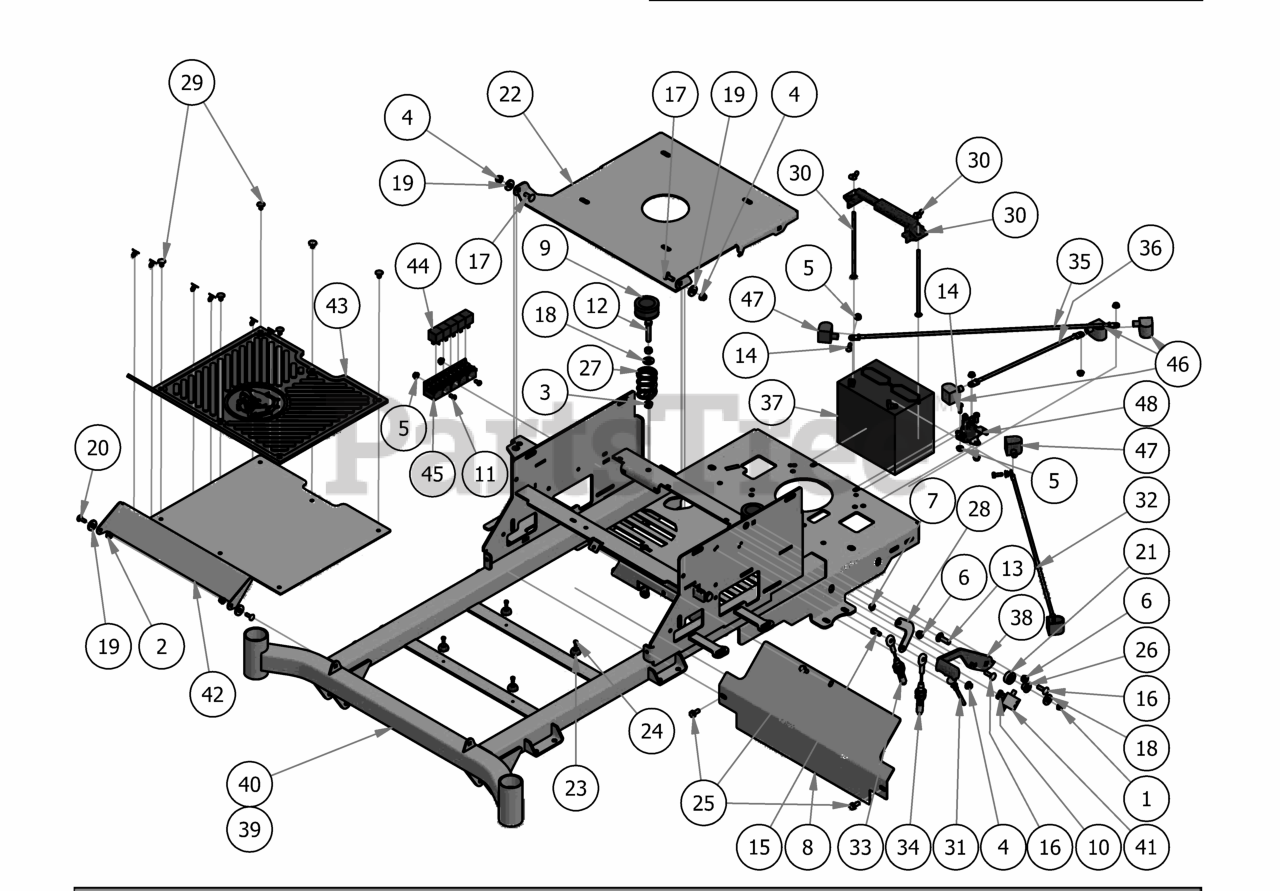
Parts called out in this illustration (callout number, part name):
1	3/8-16 Centerlock Half Nut
2	1/4-20 Nylon Insert flange Nut
3	3/8" Flange Nut
4	5/16-18 Nylong Flange Nut
5	1/4-20 Hex Flange Nuts Zinc w/Serrations
6	5/16-18 Hex Flange Nut
7	5/16-18 Nylock Jam Nut 1/2 Nut
8	2017 ZT Cooler Cover
9	Seat Spring Cap Cover
10	12-24x 1/2 HWH Bolt
11	1/4" x 1/2" BS C/S 18-8 SS
12	3/8'' x2'' Hex Bolt
13	3/8" x 1 1/4" Carriage Bolt
14	1/4" x 3/4" Hex Bolt
15	5/16" x 3/4" Hex Bolt
16	5/16" x 1" Carriage Bolt
17	5/16" x 7/8" Carriage Bolt
18	3/8" Flat Washer
19	.360 ID Plastic Washer
20	1/4" x 3/4" Carriage Bolt
21	2015 Brake Lever Spacer
22	Seat Plate 2016
23	Button Bumper
24	#10 x 1/2" Self Tapping Screw
25	5/16 x 3/4 washer head type F screw
26	Bronze Bushing SF-1220-8
27	Seat Spring
28	Brake Cable Adapter Bracket
29	5/8" Christmas Tree Fastener
30	Hold Down Assembly
32	24" Black Ground Cable
33	Brake Cable
34	Brake Cable
35	24" Red Battery Cable
36	12 in red battery cable
38	Brake Handle
39	ZT 54" and 60" Frame
40	ZT 48" Frame
41	Safety Switch
42	MZ/ZT 2017 Floorboard
43	2017 MZ/ZT Floor Mat
45	Wire Harness
47	Black Boot For Ground Cable
